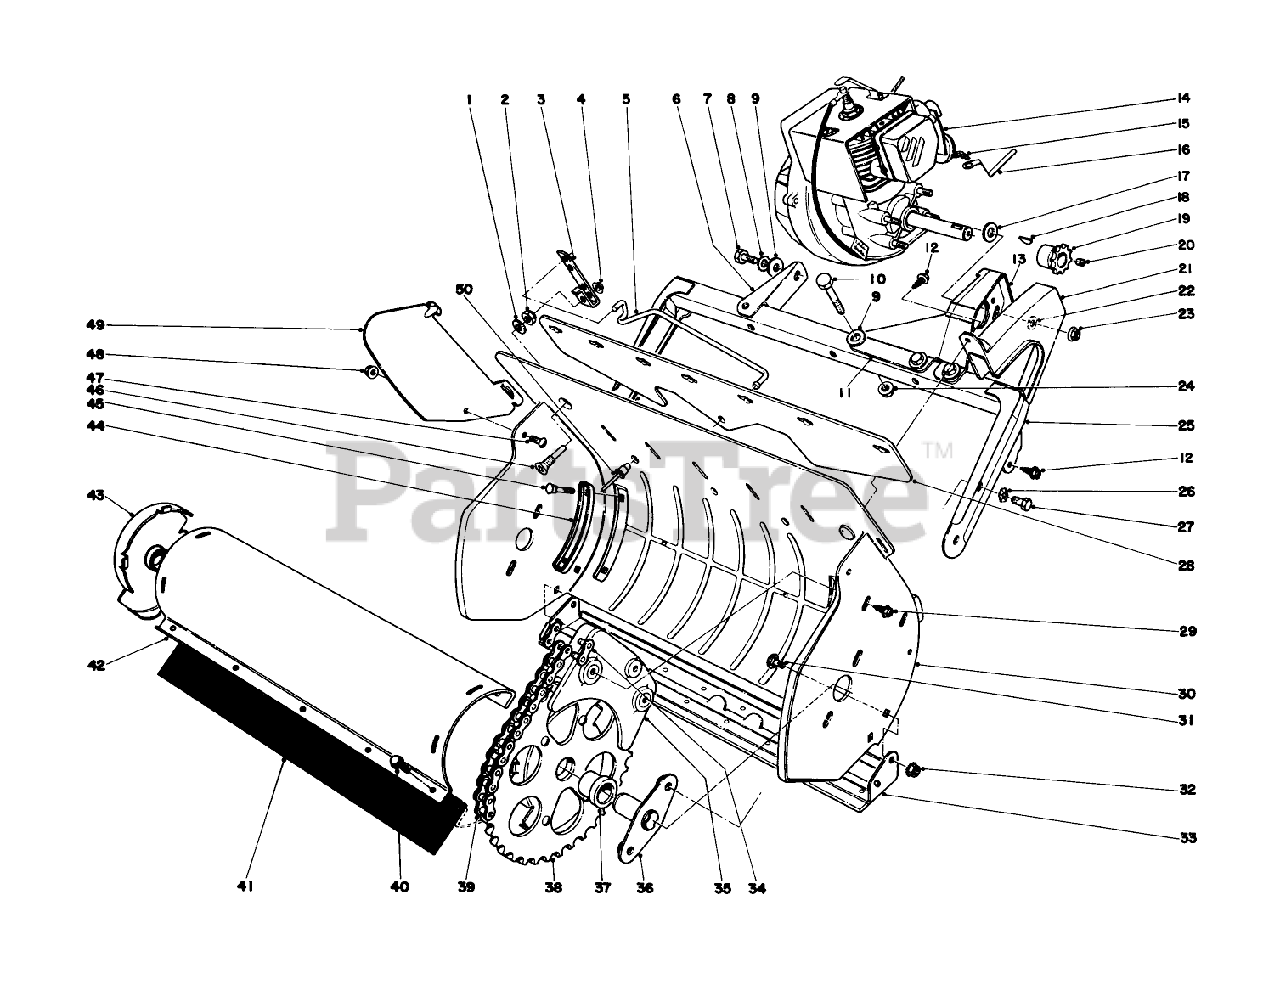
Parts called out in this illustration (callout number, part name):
1	WASHER-FLAT
2	NUT-LOCK, NI
4	NUT-SPEED
7	1/4-20 X 5/8 CAPSCREW
8	WASHER-LOCK/EXT
9	WASHER-FLAT
10	SCREW-HH
12	SCREW-HWHTF
14	Engine
17	WASHER-PLAIN
20	SCREW-SET, HSH
23	NUT-HHF
24	NUT-LOCK, HHF
30	Housing
31	SCREW-CARR
32	NUT-KEPS
34	LINK-CONNECTING, NO. 35
39	CHAIN
40	SCREW-TAP
41	ROTOR BLADE
45	SCREW-CARR
47	SCREW-PTH
48	NUT-LOCK, FLANGE
